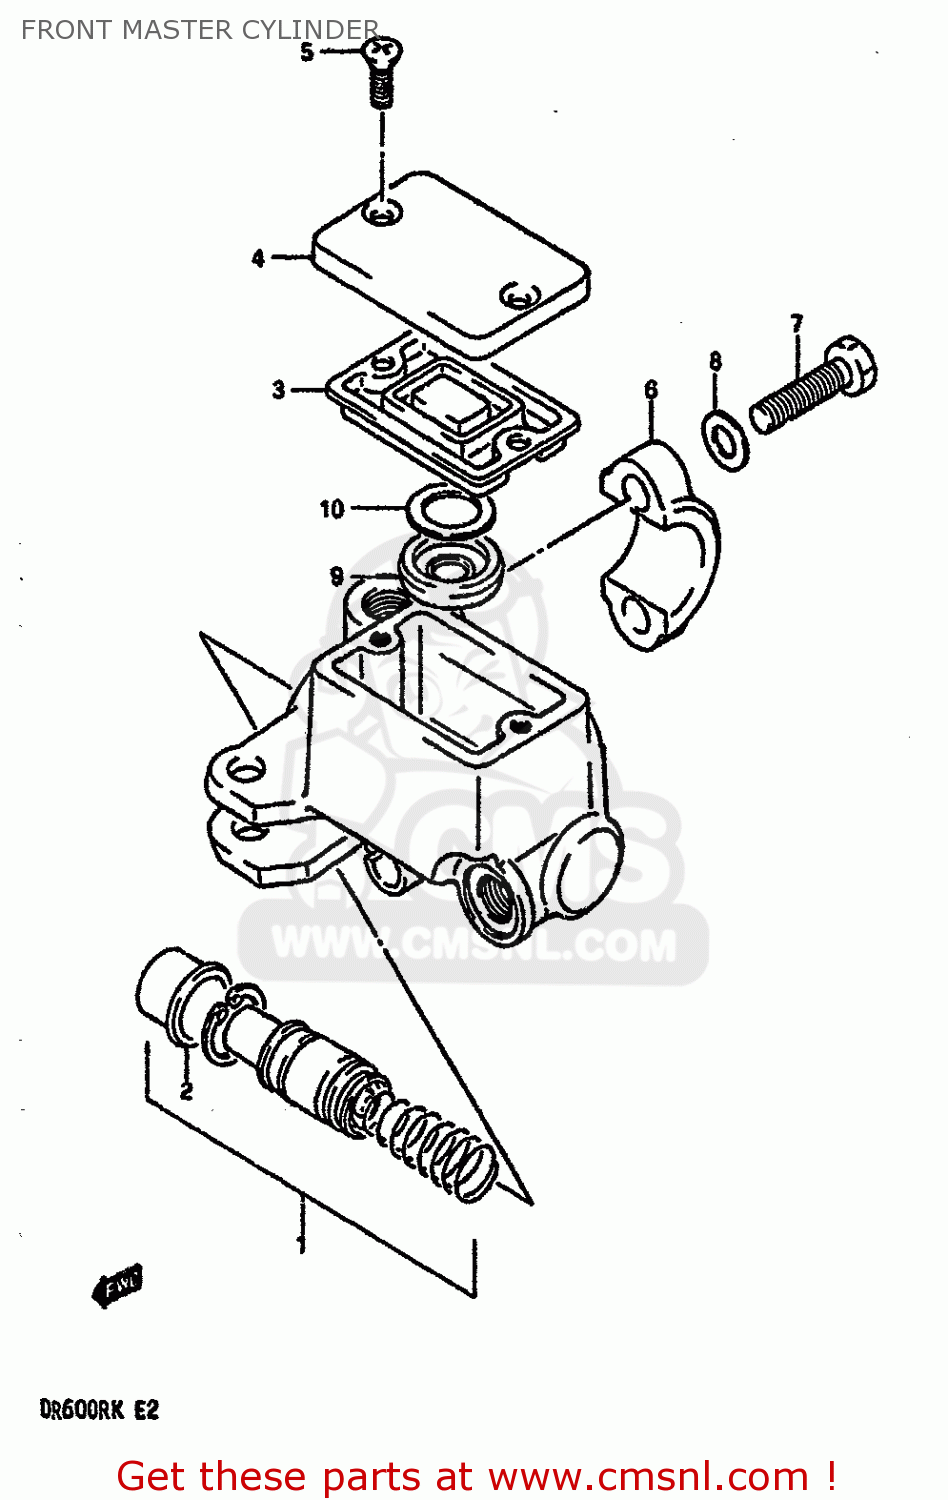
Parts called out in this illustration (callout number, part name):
1	PISTON/CUP SET
2	BOOT
3	DIAPHRAGM
4	CAP
5	SCREW
6	HOLDER
7	BOLT
8	WASHER
9	SEPERATOR
10	PLATE
